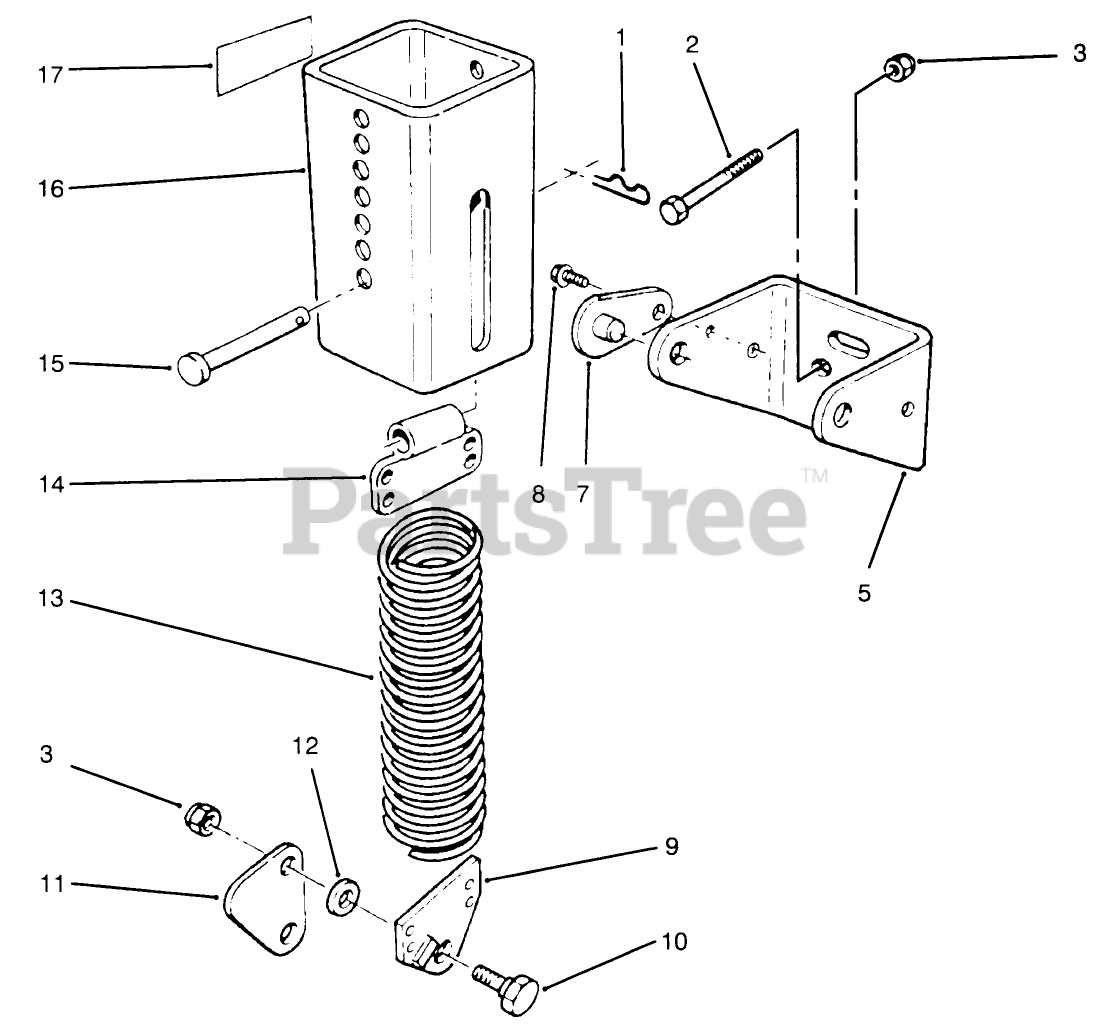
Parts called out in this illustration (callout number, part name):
1	PIN-HAIR
2	SCREW-HHF
3	NUT-LOCK, NI
5	Bracket-Mounting
7	PIN-LOCK
8	SCREW
9	End Spring
10	BOLT-SHOULDER
11	Link Knee
12	WASHER-FLAT
13	Spring-Extension
14	End Spring
15	PIN-CLEVIS
16	Asm-Spring Cover
17	DECAL-WARNING
